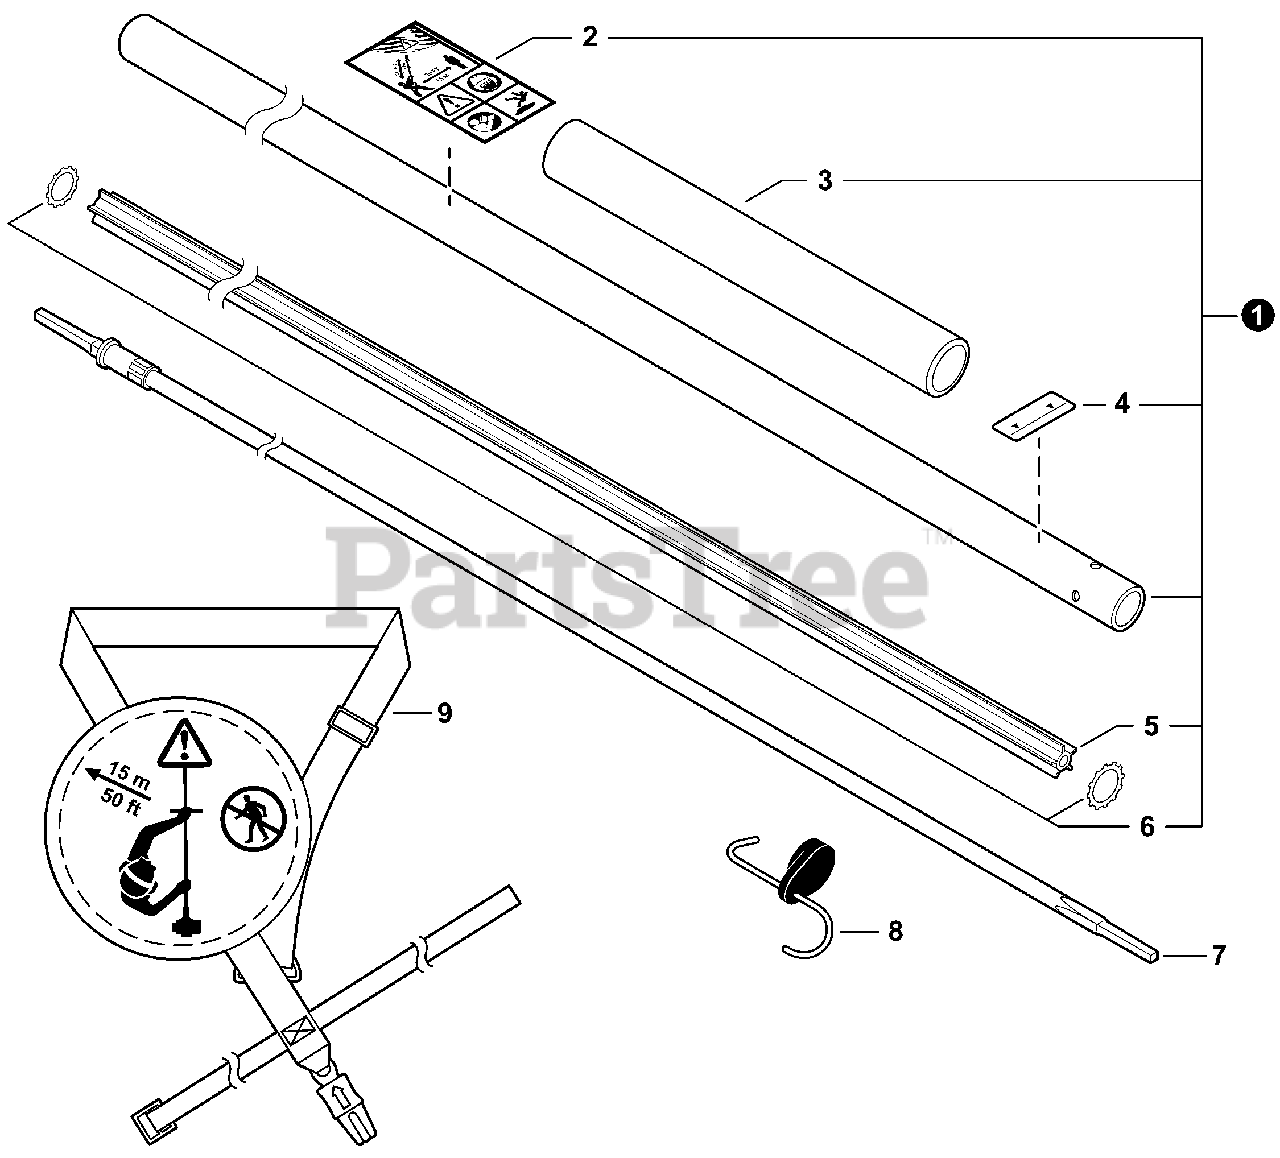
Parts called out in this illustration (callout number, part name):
1	PIPE, MAIN
2	LABEL, CAUTION
3	GRIP, HANDLE
4	LABEL, HANDLE LOCATION
5	LINER - FLEXIBLE
7	DRIVESHAFT - FLEXIBLE
8	HANGER, ATTACHMENT
9	HARNESS, SHOULDER
